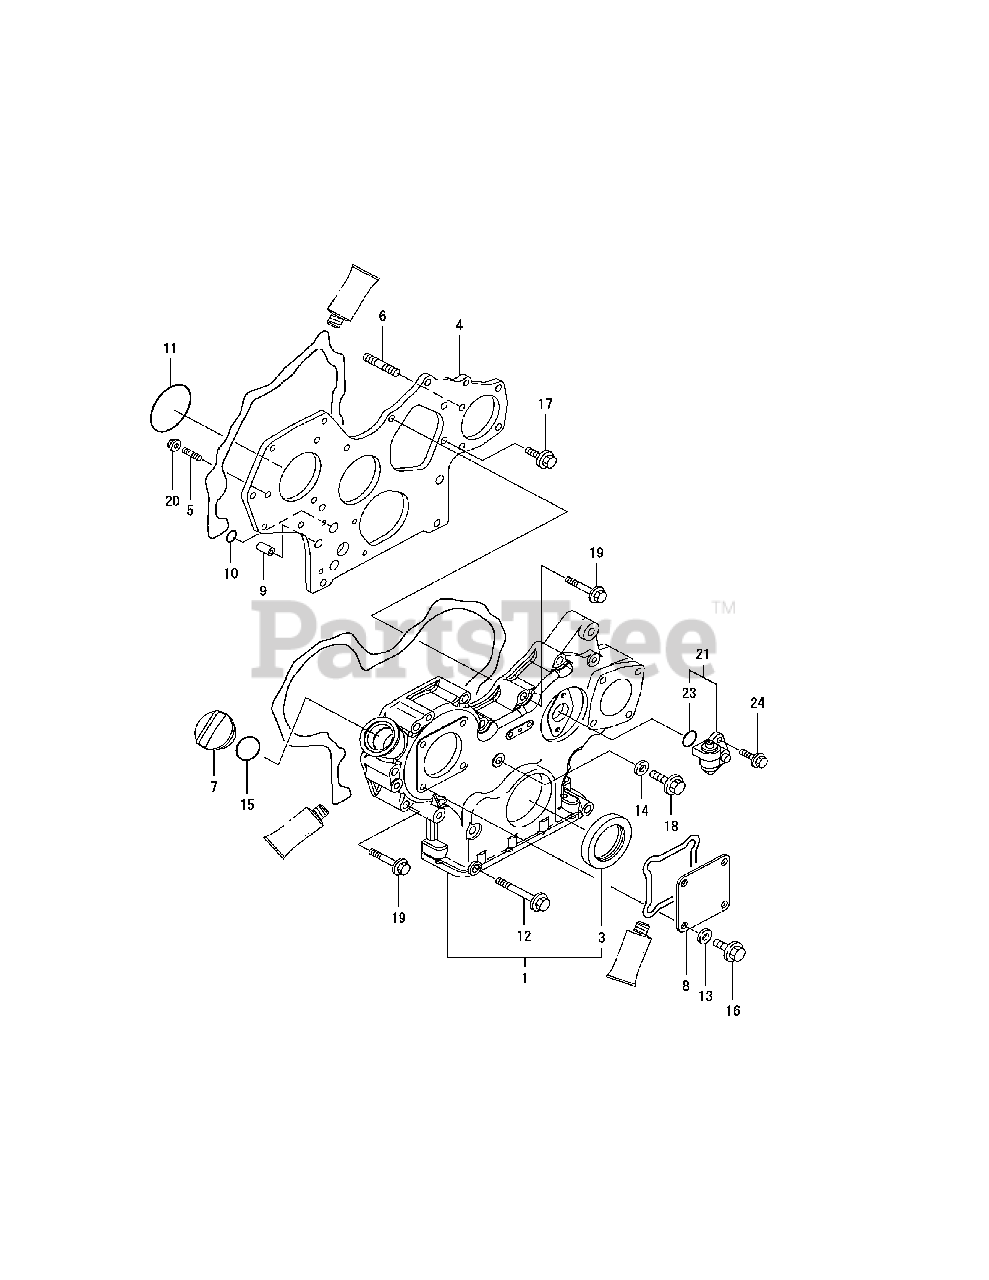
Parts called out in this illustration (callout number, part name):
1	GEAR CASE ASSY W/SEAL
4	FLANGE, GEAR CASE
9	PIPE, KNOCK L=18
11	O-RING, F.I.PUMP
12	BOLT, M8X85
13	SEAL WASHER 8S
14	SEAL WASHER 8S
15	O-RING 1A P-32.0
16	BOLT M 8X 16 PLATED
17	BOLT M 8X 16 PLATED
18	BOLT M 8X 30 PLATED
19	BOLT M 8X 55 PLATED
21	GEAR UNIT, TACHOMETER
23	O-RING 1A S-24.0
24	BOLT M 6X 16 PLATED
